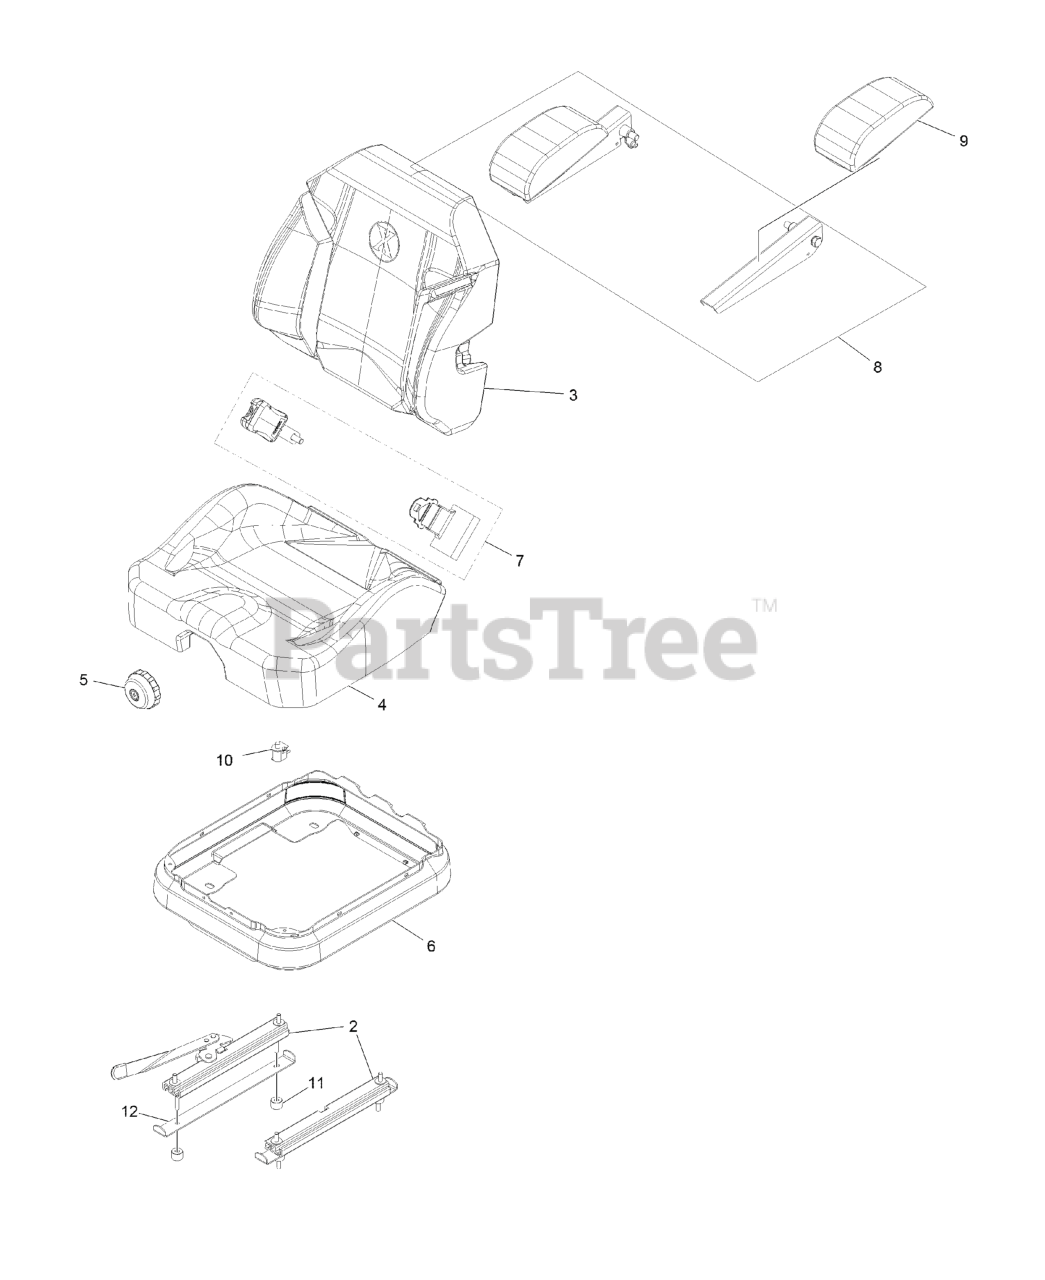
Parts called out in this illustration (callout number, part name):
2	SEAT TRACK SET
3	COVER-BACK 311463VN500
4	COVER-CUSHION 311464VN500
5	KNOB-ADJUSTER
6	COVER-SUSPENSION, BELLOWS
7	SEAT BELT SERVICE KIT
8	KIT-ARM REST SET
9	KIT-ARM REST PADS
10	SWITCH-BAIL
12	STOP, SEAT
